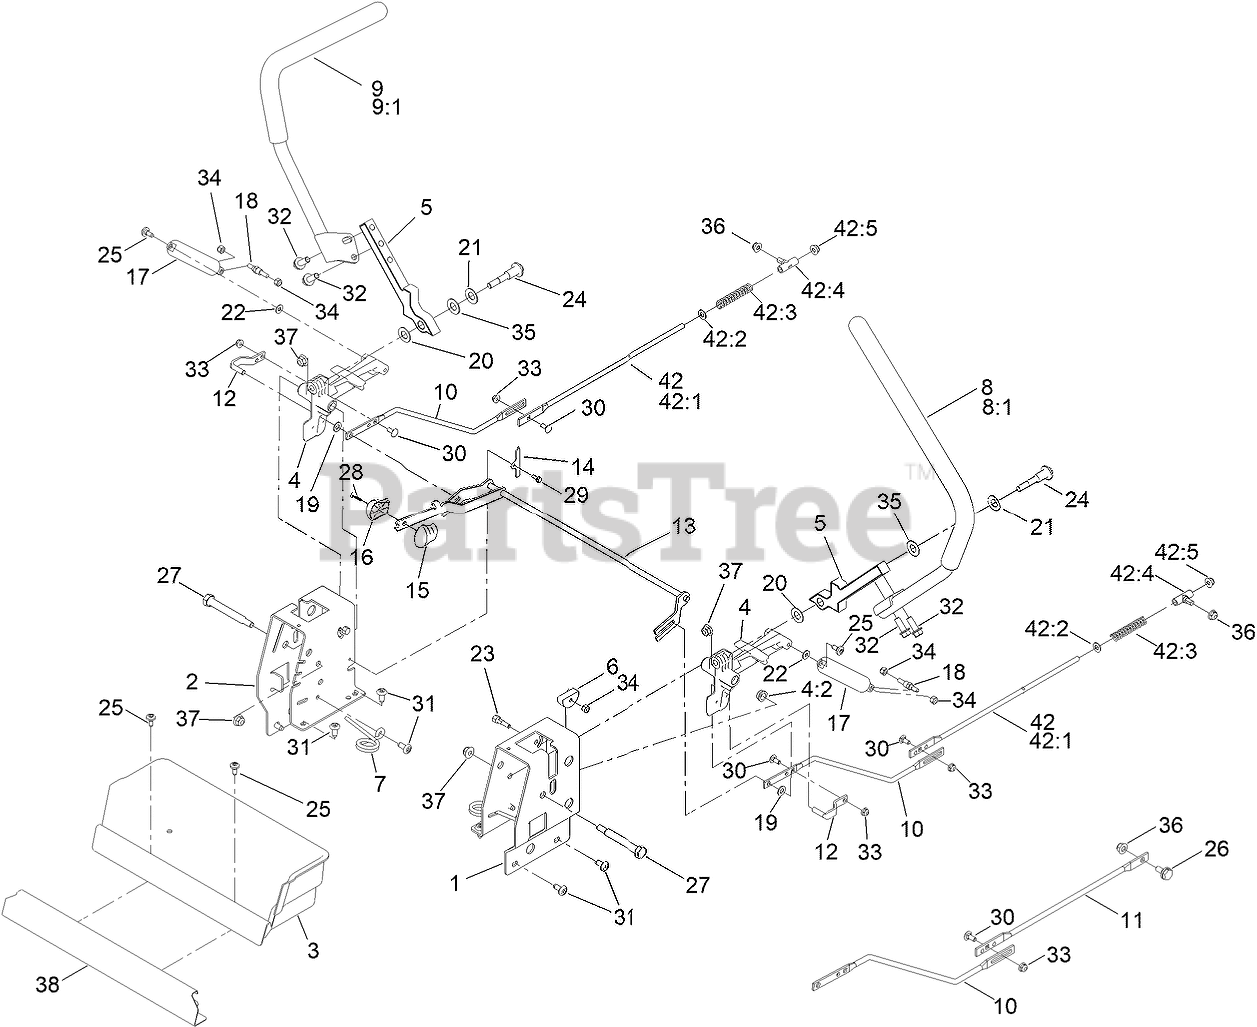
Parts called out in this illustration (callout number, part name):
1	PLATE-CONTROL BOX, LH
2	PLATE-CONTROL BOX, RH
3	BOX-STORAGE
4	ACTUATOR ARM ASM
4:2	BUSHING-FLANGE
5	ARM-CONTROL
6	ECCENTRIC
7	SPRING-TORSION
8	HANDLE-CONTROL, LH
9	HANDLE-CONTROL, RH
10	ROD-HYDRO, FRONT
11	ROD-HYDRO, REAR
12	PIN-ROD, HYDRO
13	SPEED CONTROL ASM
14	PLATE-RETAINER
15	KNOB-RH
16	KNOB-LH
17	DAMPER-NON CAVITATING
18	STUD-DAMPER
19	SPACER-NYLON
20	WASHER-NYLON
21	WASHER-BELLEVILLE
22	WASHER
23	BOLT-PIVOT, ECCENTRIC
24	BOLT-PIVOT
25	SCREW-SHOULDER
26	BOLT-SHOULDER,HFH
27	BOLT-PIVOT
28	SCREW-PPH
29	SCREW-TAPTITE
30	SCREW-CARR
32	SCREW-HHF
33	NUT-HF
34	NUT-LOCK, NI
35	WASHER
36	NUT-HF
37	NUT-HF, NI
38	PLATE-KICK
42	ROD HYDRO ASM
42:1	ROD-HYDRO, REAR
42:2	WASHER-PLAIN
42:3	SPRING-COMPRESSION
42:4	MOUNT-ROD, HYDRO
42:5	NUT-HF
